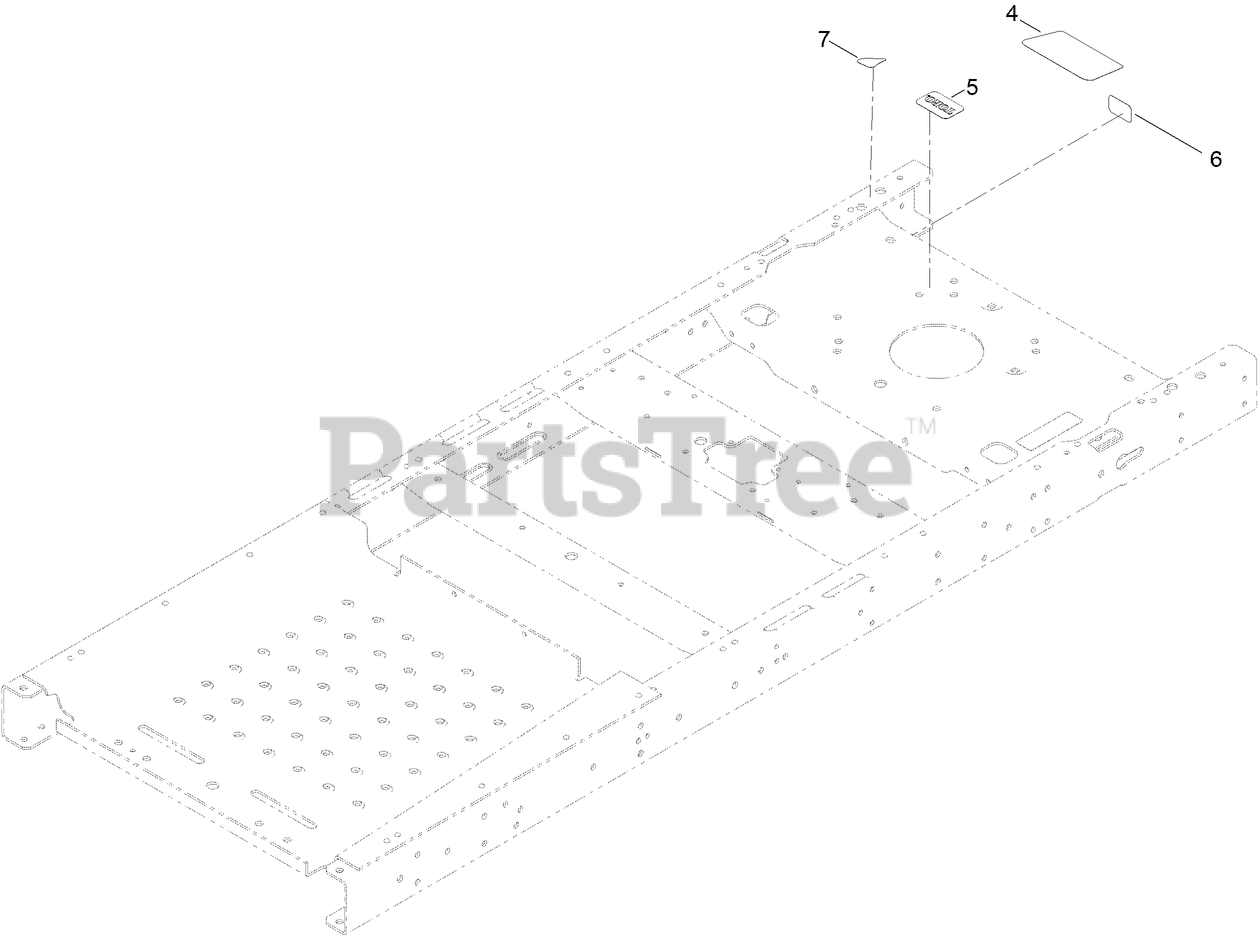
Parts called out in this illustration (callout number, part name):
4	DECAL-ENGINE
6	PLACARD-INTAKE
7	DECAL-DRAIN, OIL
